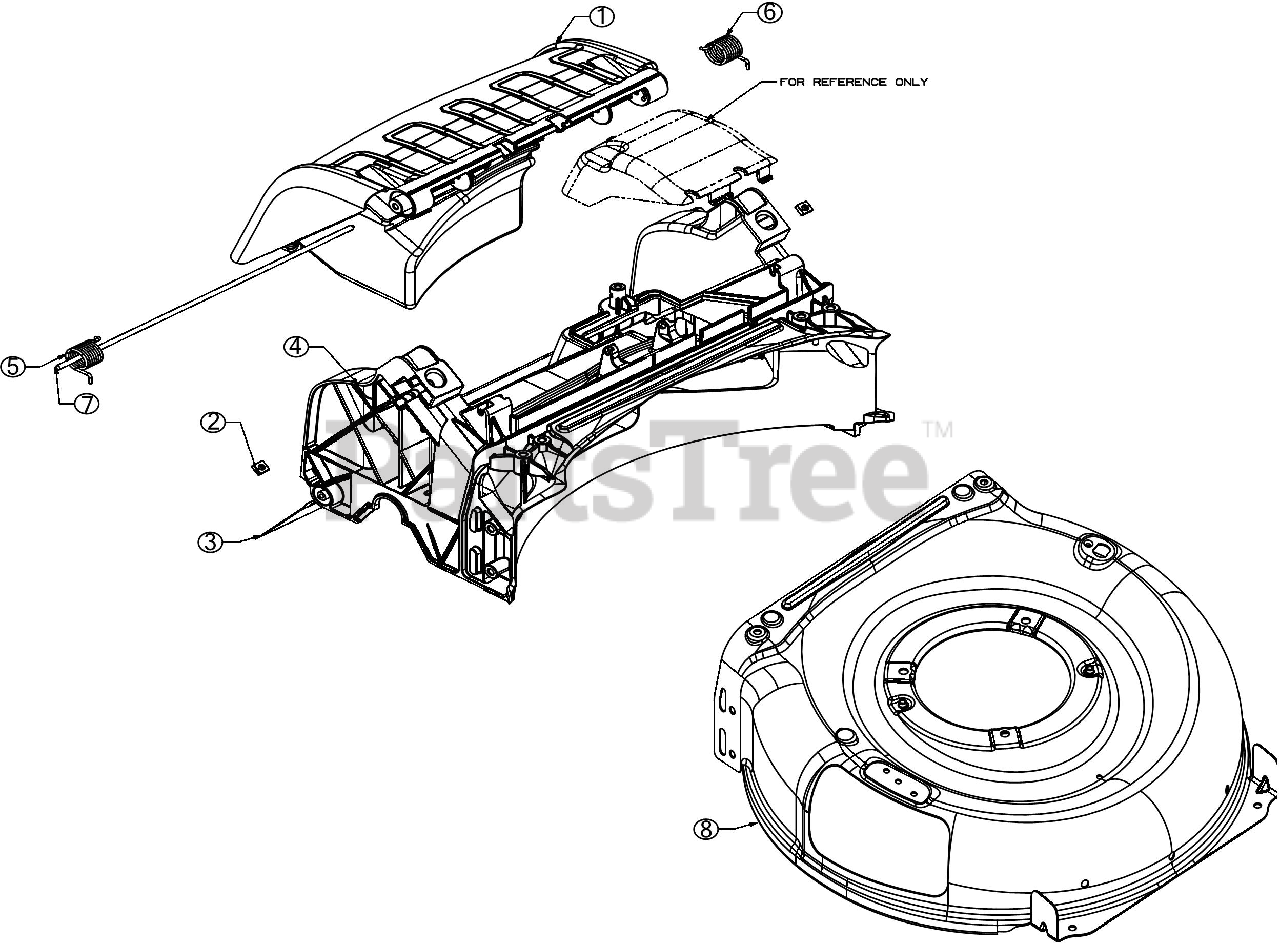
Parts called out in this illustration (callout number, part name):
2	SQUARE NUT 1/4-20
3	TRAILSHIELD
5	TORSION SPRING (RH)
6	TORSION SPRING (LH)
7	REAR DOOR PIVOT ROD
8	21" DECK (3N1)
